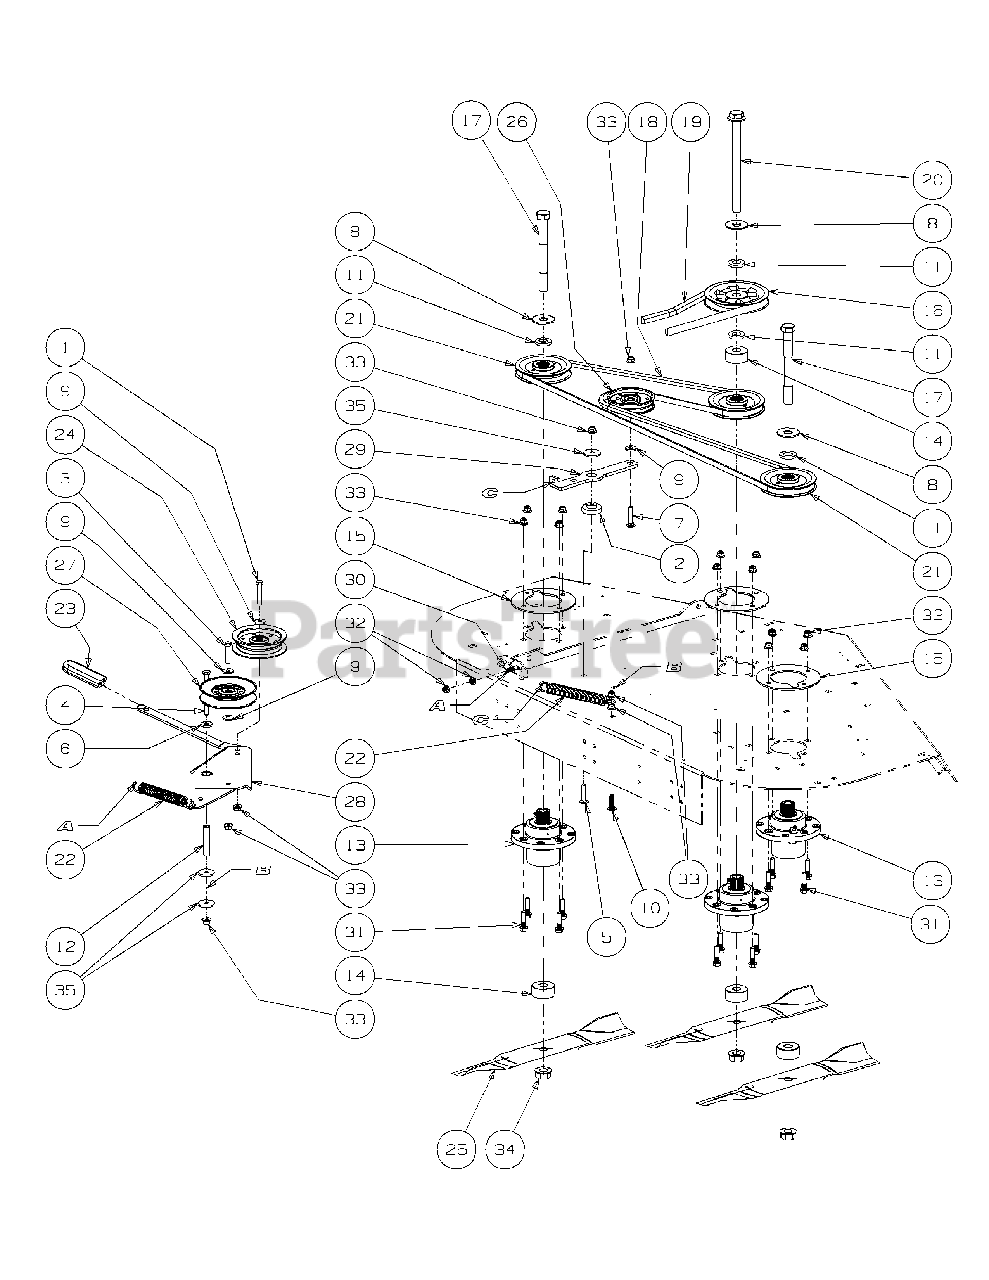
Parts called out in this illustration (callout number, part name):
1	Hex Cap Screw, 3/8-16 x 2.00
2	Shoulder Screw, .854 x .280
3	Hex Cap Screw, 3/8-16 x 1-3/4
4	Hex Cap Screw, 3/8-16, 4.00
5	Carriage Bolt, 3/8-16 x 1-1/2
6	Flat Washer, 3/8
7	Hex Carriage Screw, 3/8-16, 1.75
8	Flat Washer, .781 ID, 2.00 OD, .105
9	Flat Washer, .406 ID, 1.0 OD, .105
10	Carriage Bolt, 3/8-16 x 1-1/4
11	Spacer, .812 ID x .218 LG
12	Spacer, .39 ID x .625 OD x 2.75
13	Spindle Assembly, Aluminum Fab Deck
14	Spacer, .760 ID x 2.000 OD x 1.1
15	Plate Support, Cast Aluminum Spindle
16	V Pulley, 5.774 OD
17	Hex Cap Screw, 3/4-16, 7.00
18	V Belt, A Section x 114.3
19	V Belt, B Section x 91.2
20	Hex Cap Screw, 3/4-16, 9.00
21	V Pulley, 5.00 OD
22	Spring Extension, .94 OD x 7.57
23	Idler Tension Handle Grip
24	Idler Pulley, 4.06 OD w/Deep Flange
25	Hi-Lift Blade, 19.0, 0.756
26	Idler Pulley, 4.06 Dia.
27	Idler Pulley, 5.06 Dia.
28	Idler Arm Assembly includes:
28	Bearing
30	Carriage Bolt, 5/16-18 x 1.50
31	Bolt, 3/8-16 x 1.5
32	Nut, 5/16-18, Nylon Flange Lock
33	Nut, 3/8-16, Nylon Flange Lock
34	Flange Hex Nut, 3/4-16
35	Washer, .390 x 1.500 x .134
